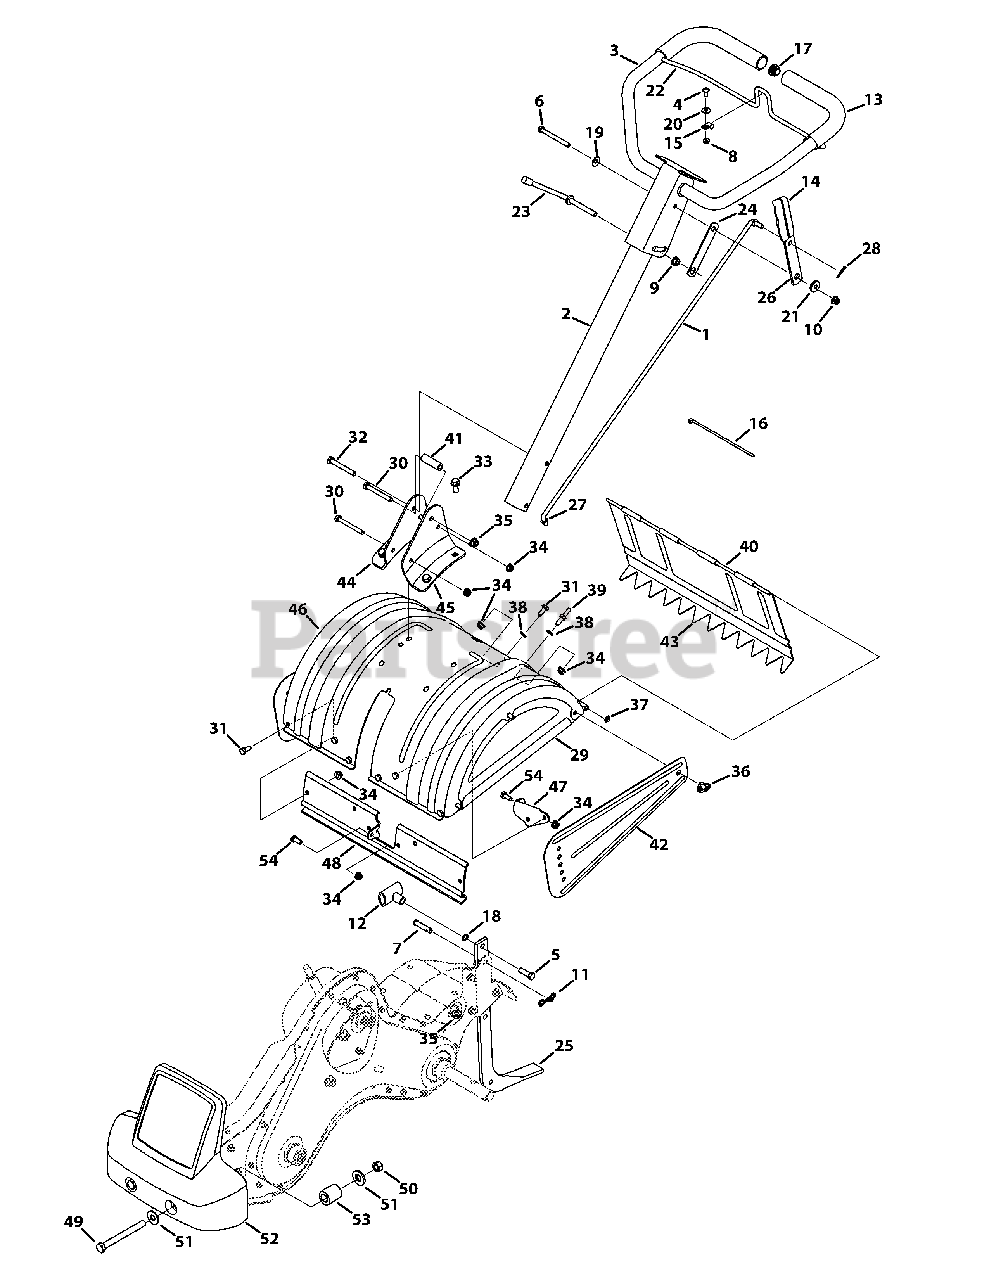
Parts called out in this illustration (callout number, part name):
1	Shaft Rod
2	Lower Handle Tube Assembly
3	Upper Handle Assembly
4	Screw, 1/4-20 x 0.625
5	Hex Head Screw, 3/8-16:1.25
6	Hex Head Screw, 5/16-18 x 3.25
7	Clevis Pin, .375 X 1.75
8	Nylon Hex Lock Nut, 1/4-20
9	Flangelock Nut, 3/8-24
10	Hex Flange Top L-Nut, 5/16-18
11	Internal Cotter Pin
12	Small Tee Knob
13	Foam Grip, .970 x 11.0
14	Grip, .1875 x 1.00
15	Battery Clamp, 5/16
16	Cable Tie, 8.5 LG
17	End Plug
18	Washer, Flat, .385 x .620 x .033
19	Washer, Bell, .340 x .872 x .060
20	Washer, Flat, .260 x .720 x .060
21	Spacer, Shoulder, .50 x .190 x .360 LG
22	Clutch Bail
23	Handle Adjustment Crank
24	Hex Nut Retainer Bracket
25	Tiller Depth Control
26	Shaft Rod Lever
27	Washer, Rubber, .33 ID x .87 OD x .125
28	Cotter Pin, .072 x 1.12 LG
29	End Cover Assembly
30	Hex Head Screw, 5/16-18 x 2.75
31	Hex Head Screw, 5/16-18 x .75
32	Hex Head Screw, 3/8-16 x 2.75
33	Hex Head Flange, 3/8-16 x .875
34	Flangelock Nut, 5/16-18
35	Flangelock Nut, 3/8-16
36	Wing Nut, 5/16-18 W/ Bell Washer
37	Speed Nut Cap, 1/4 ROD
38	Washer, Flat, .344 x .62 x .033
39	Screw, Hex, 5/16-18 x .75
40	Tiller Flap Rod
41	Spacer, .322 x .625 x 2.00
42	Side Shield
43	Rear Tine Shield
44	RH Handle Mount Bracket
45	LH Handle Mount Bracket
47	FRT Tine Shield Bracket
48	FRT Tine Shield Spacer Bracket
49	Hex Head Screw, 1/2-13 x 5.50
50	Hex Nut, 1/2-20
51	Washer, 1/2 x 1.25 x .10
52	Counterweight
53	Hub, .636 ID x 1.00 OD x .94
54	Hex Head Screw, 5/16-18 x 1.00
